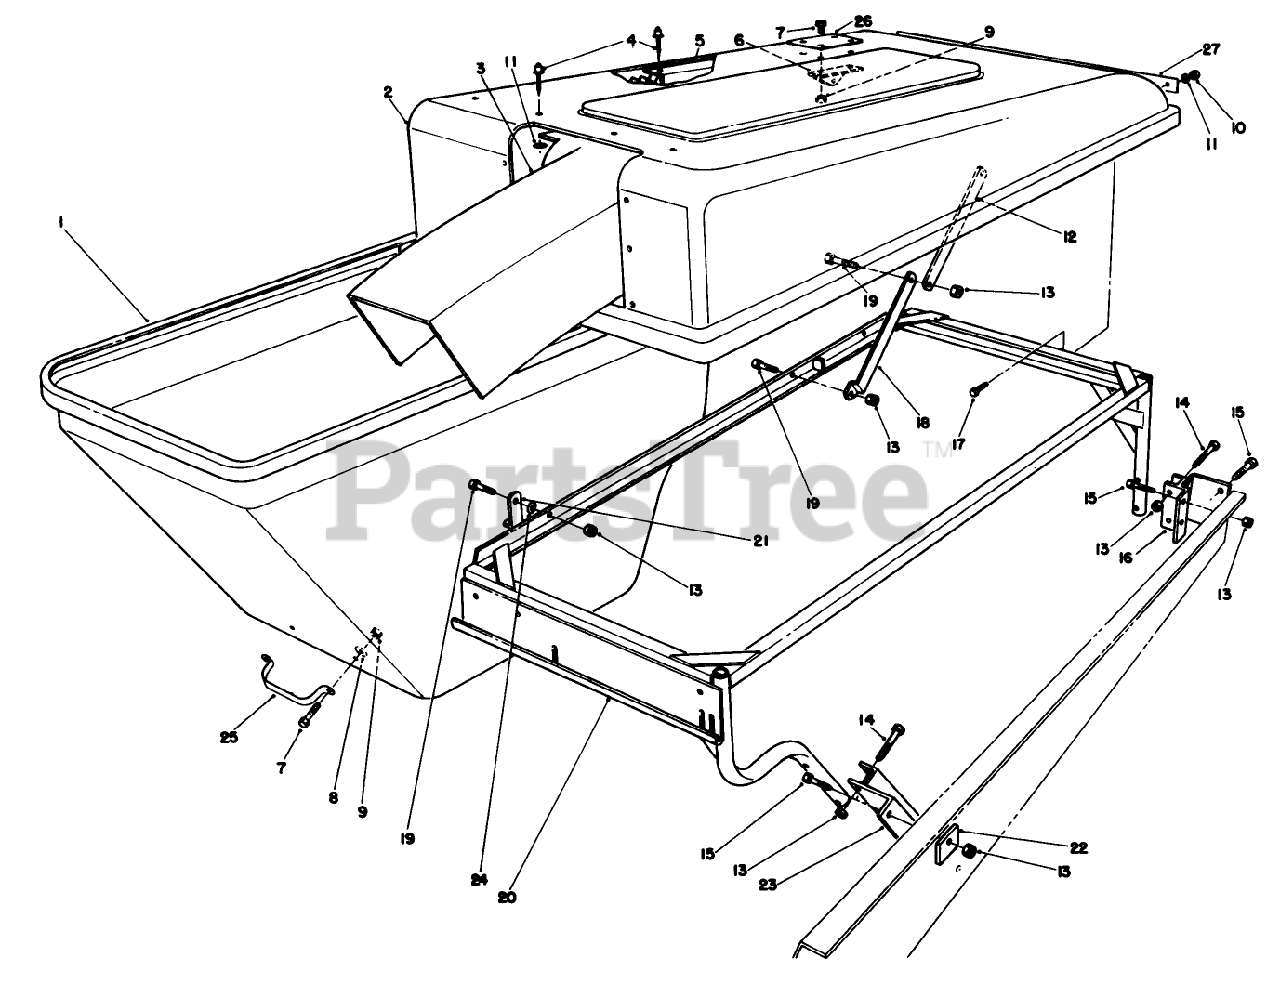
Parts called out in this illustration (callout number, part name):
1	BAGGER HOPPER
2	BAGGER HOOD
3	BAGGER SNOUT
4	RIVET-POP
5	Bagger Screen
6	Pivot-Bagger
7	SCREW-HH
8	Washer-Flat
9	NUT-LOCK, NI
10	NUT-LOCK, NI
11	WASHER-FLAT
12	Link
13	NUT-LOCK, NI
14	SCREW-HH
15	Hex Hd. Capscrew
16	Bracket-Rear
18	Link-Bag
19	SCREW-HH
20	HOPPER FRAME WA
21	Latch-Hopper
22	Plate-Reinforcing
23	Bracket-Front
24	WASHER-SPRING
25	Handle
26	HOOD PLATE
27	HINGE PLATE
